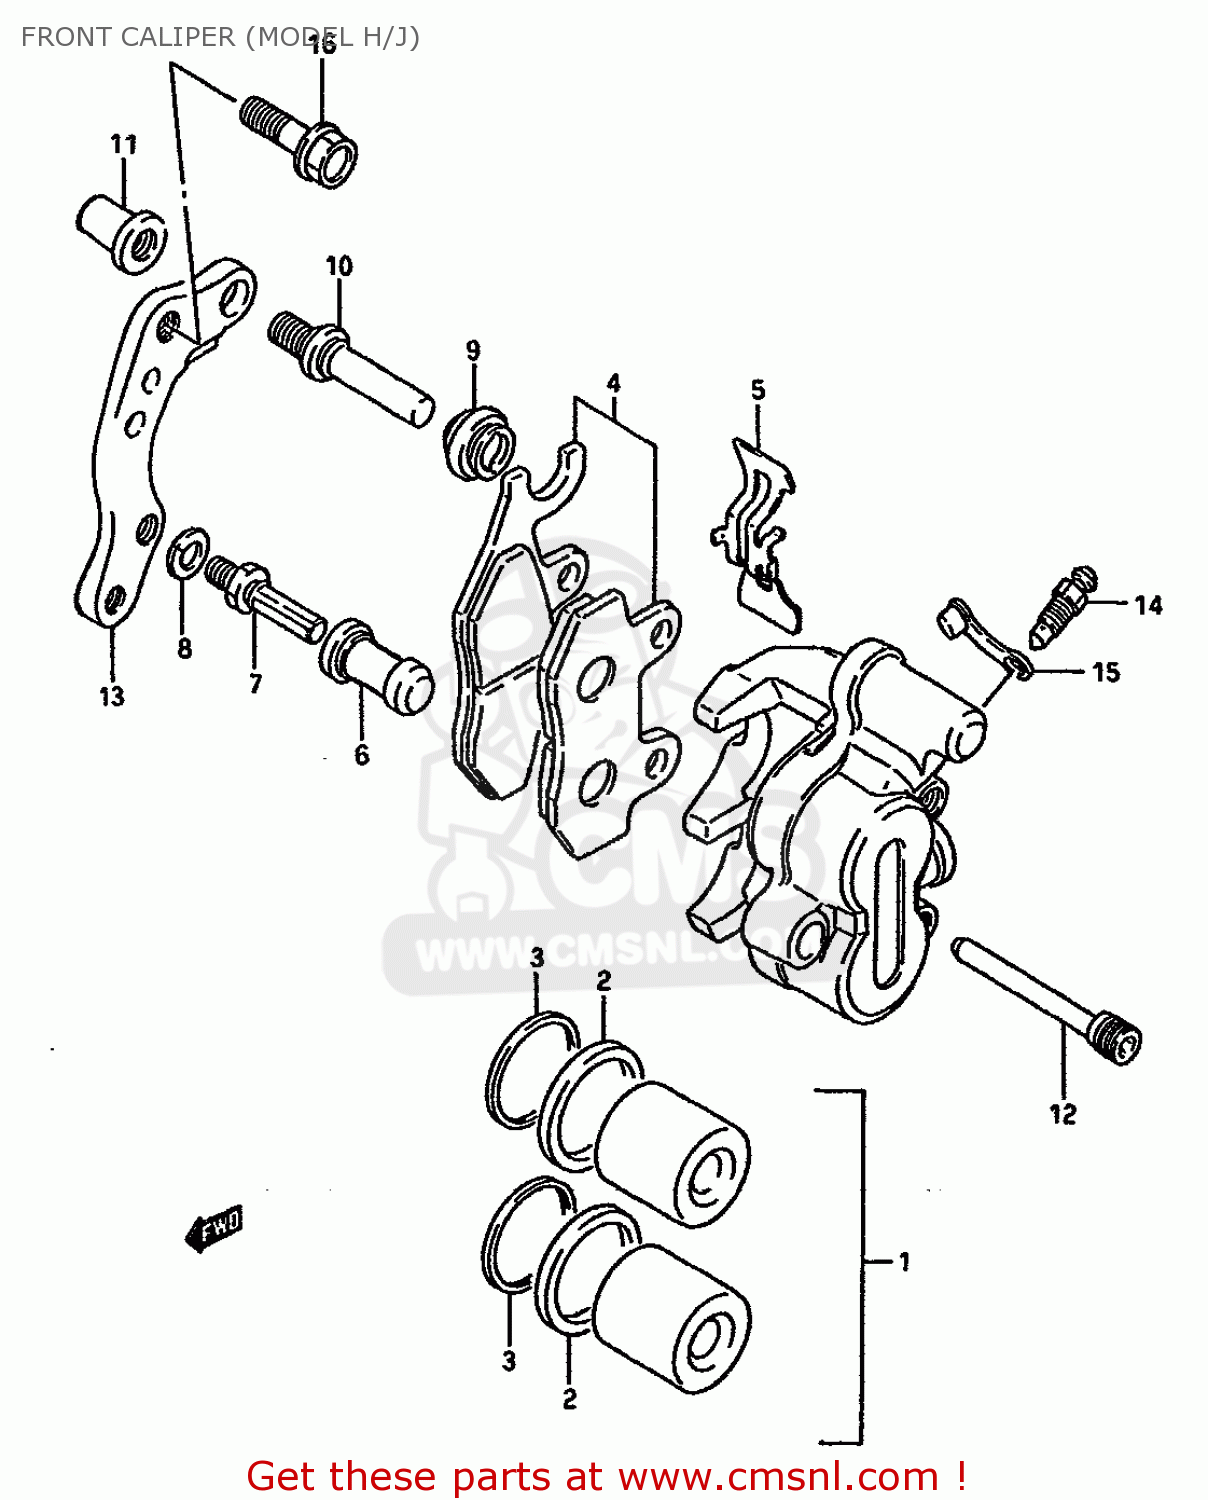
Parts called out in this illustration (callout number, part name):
1	PISTON SET
2	SEAL,PISTON
3	SEAL,DUST
4	PAD SET (MCA)
5	SPRING
6	BOOT
7	BOLT,PIN
8	WASHER,WAVE
9	BOOT
10	PIN,SLIDE
11	NUT
12	PIN,HOLDER
13	BRACKET
14	BLEEDER
15	CAP,BLEEDER
16	BOLT(8X24)
